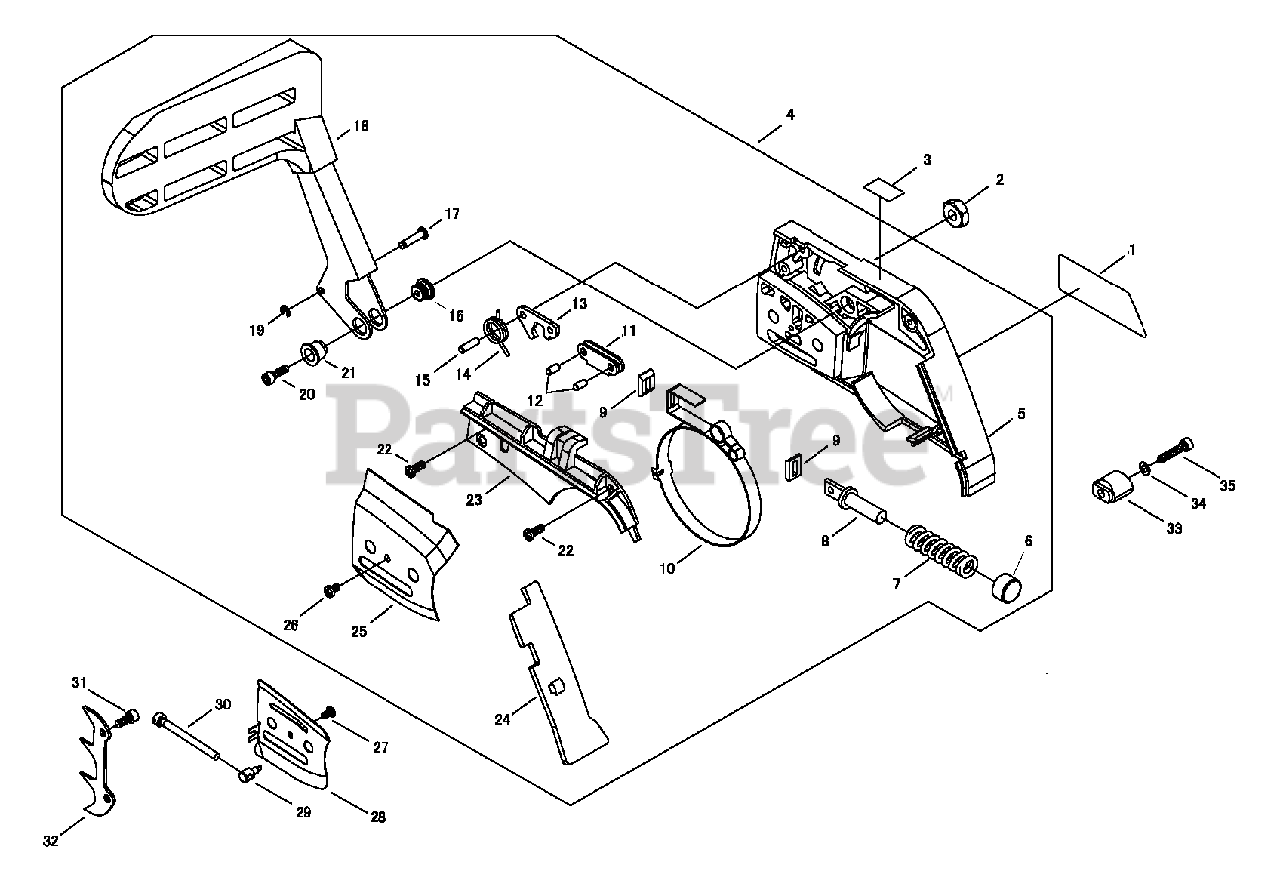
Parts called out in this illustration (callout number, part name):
1	LABEL, TRADE
3	LABEL, CHAIN BRAKE
4	BRAKE ASSY
5	GUARD, SPROCKET
6	STOPPER
7	SPRING, BRAKE
8	HOLDER, SPRING
9	PLATE, ADJUST
10	BAND, BRAKE
11	STRAP, TIE
12	PIN, LOCATING Ø4×8
13	LEVER, INNER
14	SPRING, LEVER
15	PIN, LOCATING
17	PIN, LEVER
18	LEVER, BRAKE
19	RING, SNAP 3 MM
20	BOLT 4×12
22	SCREW, TAPPING 4×12
24	PROTECTOR
25	PLATE, GUIDE - INNER
26	SCREW, TAPPING 4×8
27	SCREW M4×7
28	PLATE, GUIDE
29	TENSIONER, CHAIN
30	SCREW, SLIDE
32	SPIKE, BUMPER
33	CHAIN CATCHER
34	WASHER 5 MM
35	BOLT M5×25
